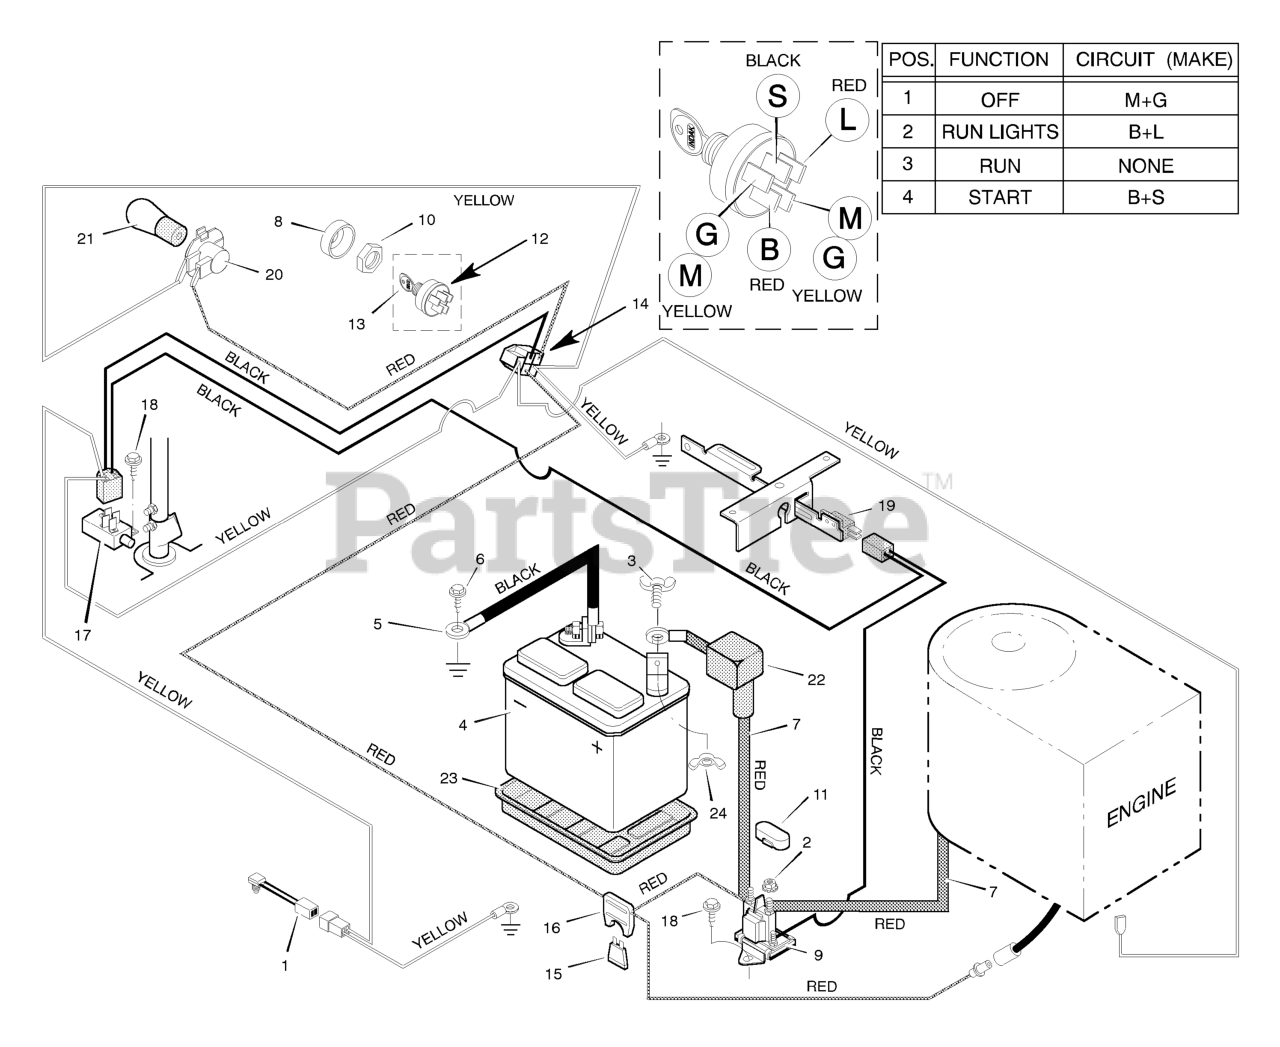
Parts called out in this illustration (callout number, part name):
1	Switch, Seat Sensor
2	Locknut
4	Battery
5	Cable, Battery Ground
7	Cable, Red Battery
8	Cap, Ignition
9	Solenoid
10	Nut, Hex
11	Cover, Solenoid
12	Switch, Ignition
13	Key, Ignition
14	Harness, Chassis Wire
16	Holder, Fuse
17	Switch, Limit
19	Switch, Limit
20	Socket, Light
21	Bulb, Light
22	Cover, Terminal
23	Tray, Battery
24	Wingnut
